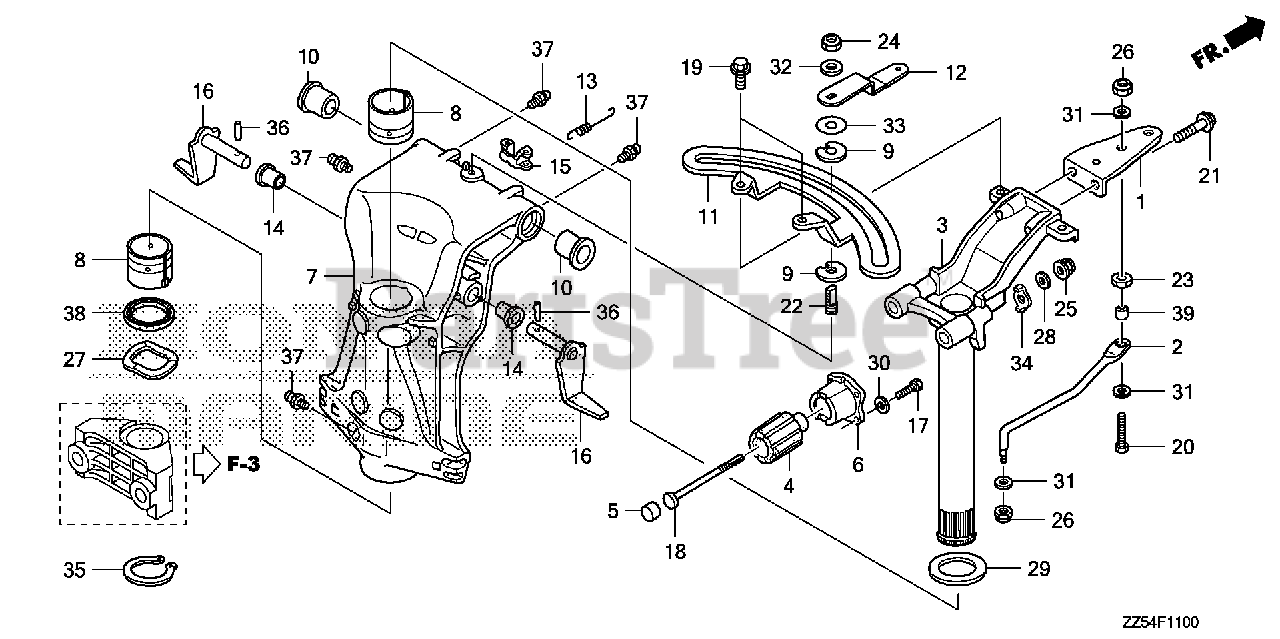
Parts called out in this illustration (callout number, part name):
3	FRAME, MOUNTING
4	RUBBER, MOUNTING (UPPER)
5	RUBBER, MOUNTING (UPPER) (B)
6	HOLDER, MOUNTING (UPPER)
7	CASE, SWIVEL *NH282MU* (OYSTER SILVER METALLIC-U)
8	LINER, SWIVEL CASE
9	BLOCK, FRICTION
10	BUSH, SWIVEL CASE
11	PLATE, FRICTION
12	LEVER, FRICTION
13	SPRING, TILT LEVER
14	BUSH, TILT ARM
15	BRACKET, TILTING
16	STOPPER, TILT
17	BOLT, HEX. (6X18)
18	BOLT, SPECIAL (10X130)
19	BOLT, FLANGE (6X12) Use from Frame SN 1005249.
22	BOLT, STUD (8X26)
24	NUT, SELF-LOCK (8MM)
25	NUT, FLANGE (10MM)
27	WASHER, WAVE (40MM)
28	WASHER, PLAIN (10MM)
29	WASHER, THRUST (34MM)
30	WASHER, PLAIN (6MM) Use up to Frame SN 4800342.
32	WASHER (8MM)
33	WASHER, NYLON (8MM)
34	WASHER, SPECIAL
35	CIRCLIP (OUTER) (39MM)
36	PIN, SPRING (2.5X20)
37	NIPPLE, GREASE
38	OIL SEAL (39.5X52X6) (ARAI)
